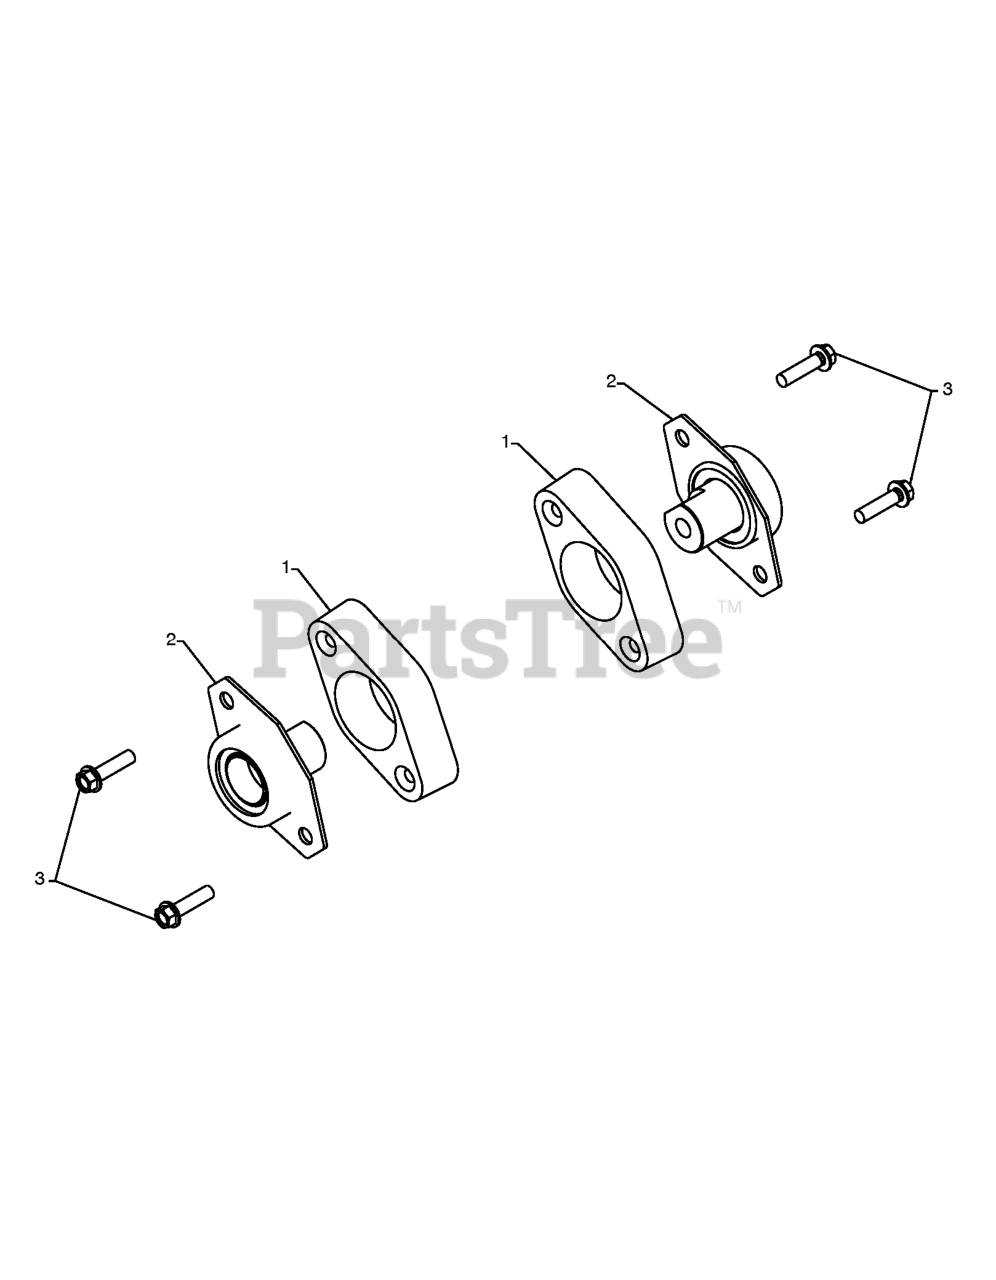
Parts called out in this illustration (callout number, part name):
1	BEARING RETAINER, PLASTIC
2	BEARING.BALL.AUGER
3	SCREW, HEX HD 5/16X1
